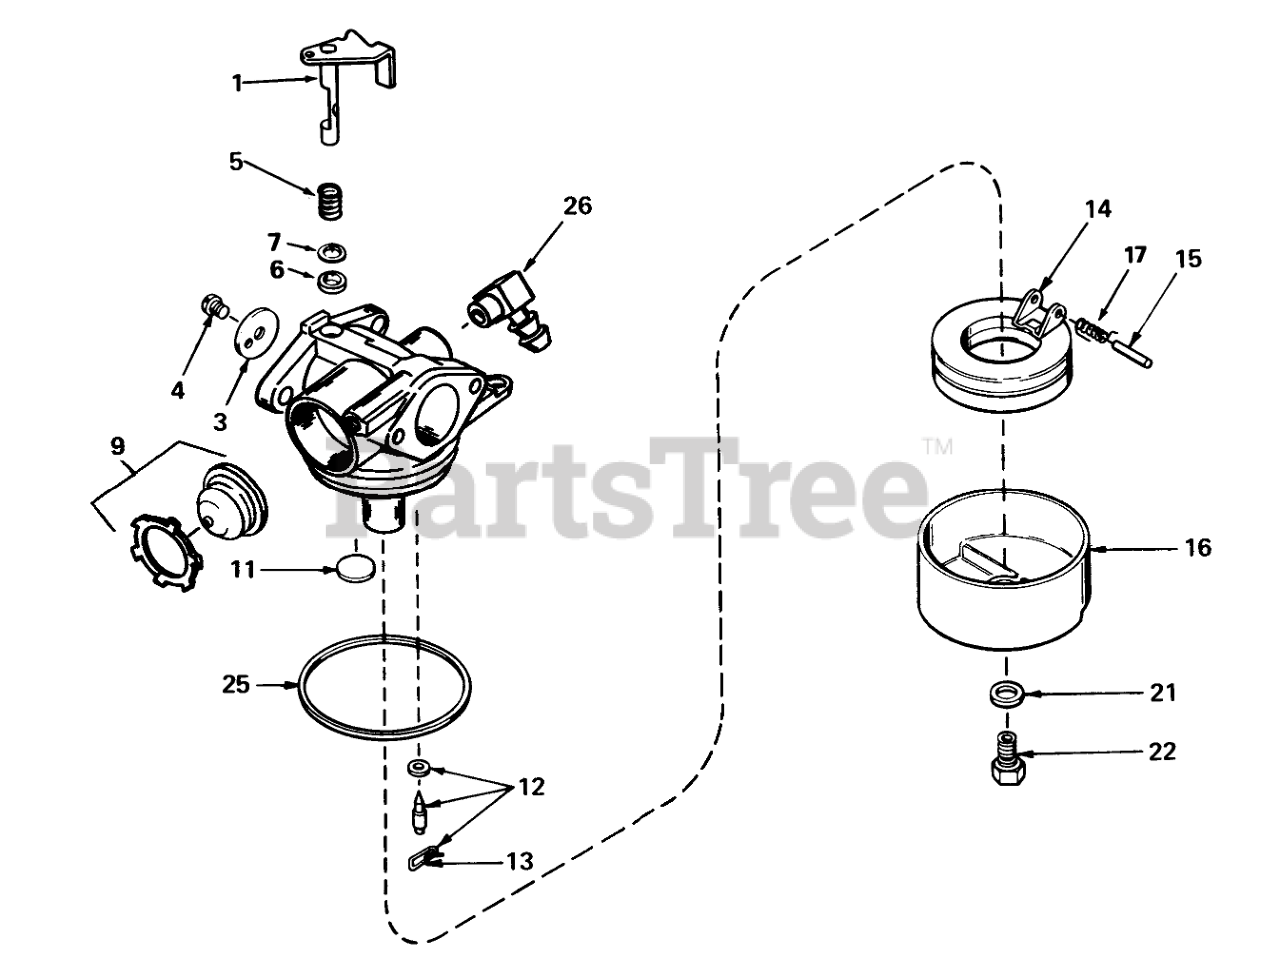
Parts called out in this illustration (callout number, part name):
1	Throttle Shaft & Lever Assy.
3	Shutter-Throttle
4	Screw-Shutter
5	Spring-Trottle, Return
6	Seal-Dust
7	Washer-Seal, Dust
9	Bulb-Primer
11	Plug-Welch, Atmospheric Vent
12	Needle Seat & Clip Assy. (Incl. Ref. #13)
13	Clip-Spring
14	Float
15	Shaft-Float
16	Bowl-Float (no drain)
17	Spring-Float, Dampening
21	Washer-Bowl Nut
22	Nut-Float Bowl
25	O Ring-Bowl, Float
26	Fitting-Fuel
